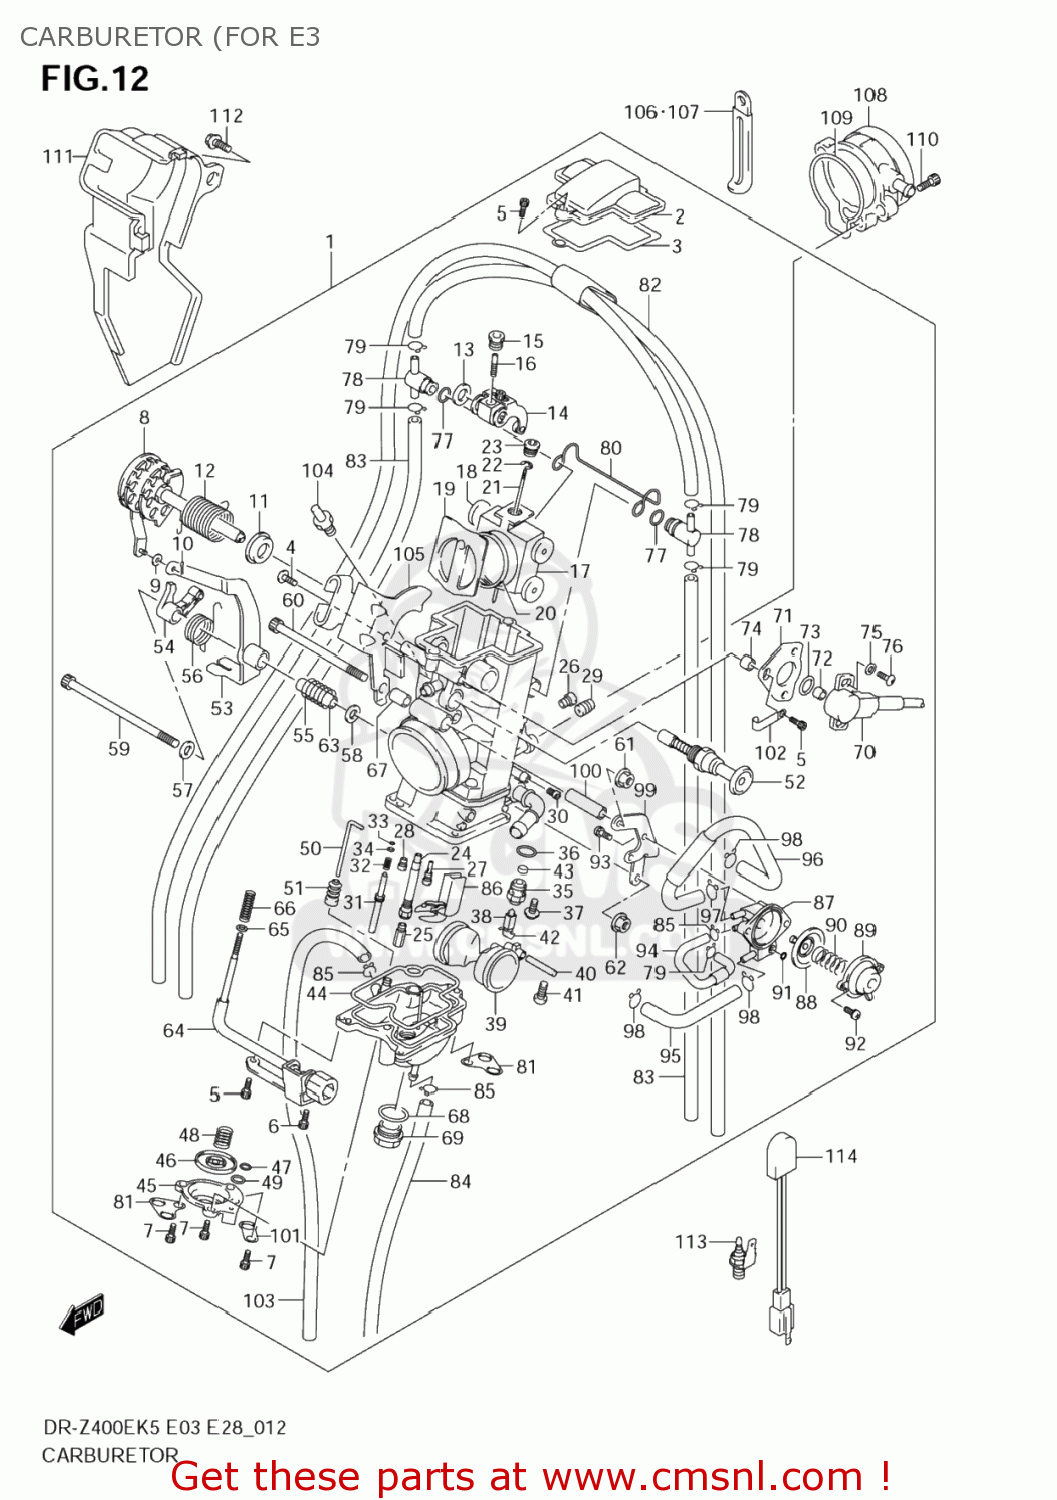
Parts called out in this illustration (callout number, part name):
1	CARBURETOR ASSY
2	3
3	TOP WASHER
4	BOLT
5	6
6	7
7	BOLT(4X8)
8	SHAFT,THROTTLE
9	WASHER
10	PIN
11	COLLAR
12	SPRING
13	WASHER
14	LINK ARM
15	NUT
16	SCREW
17	VALVE,THROTTLE
18	BEARING
19	VALVE
20	LIP SEAL
21	NEEDLE,JET
22	23
23	SCREW,NEEDLE SET
24	MAIN NOZZLE
25	JET,MAIN(142)
26	JET,MAIN AIR(200)
27	JET,SLOW(45)
28	JET,STARTER(65)
29	JET,SLOW AIR(60)
30	JET,AIR(90)
31	SCREW,ADJUST
32	SPRING
33	O RING
34	WASHER
35	VALVE SEAT
36	O RING
37	38
38	VALVE,FLOAT
39	FLOAT
40	41
41	42
42	CLIP
43	SCREEN,FUEL STRAINER
44	PACKING (NAS)
45	COVER
46	DIAPHRAGM
47	U RING
48	SPRING
49	O RING
50	ROD
51	CAP
52	VALVE,STARTER
53	54
54	LINK LEVER
55	SPRING
56	SPRING
57	WASHER
58	COLLAR
59	BOLT
60	BOLT
61	NUT
62	NUT
63	COLLAR
64	SCREW,STOP
65	66
66	67
67	COLLAR
68	69
69	BOLT
70	SENSOR,THROTTLE
71	PLATE
72	COLLAR
73	O RING
74	COLLAR
75	WASHER
76	SCREW
77	O RING
78	JOINT
79	CLIP
80	CLIP
81	PLATE
82	PIPE
83	PIPE
84	PIPE,RUBBER
85	CLIP
86	PLATE
87	BODY,DIAPHRAGM
88	DIAPHRAGM
89	COVER
90	91
91	U RING
92	SCREW
93	SCREW
94	PIPE,RUBBER
95	PIPE,RUBBER
96	97
97	CLIP
98	99
99	PLATE,STAY
100	COLLAR
101	PLATE
102	BINDER
103	PIPE
104	SCREW,STOP
105	PLATE STAY
106	CLAMP(L:65)
107	CLAMP(L:120 T:1.0)
108	JOINT,AIR CLEANER
109	O RING,AIR CLNR JOINT
110	BOLT
111	COVER,CARBURETOR
112	BOLT
113	HEATER ASSY,CARBURETOR(15W)
114	THERMO SWITCH,CARB HEATER
